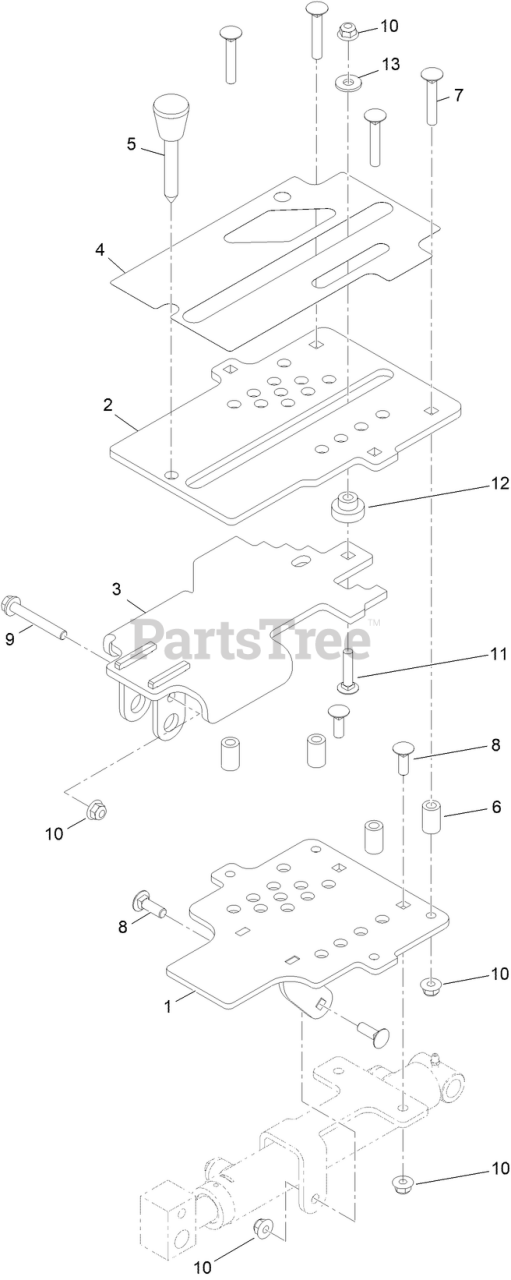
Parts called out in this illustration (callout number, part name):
1	GAUGE-DEPTH, AERATOR
2	PLATE-GAUGE, DEPTH
3	STOP-DEPTH
4	DECAL-DEPTH INDICATOR
5	PIN-HOC
7	Bolt-Carriage 3/8-16 X 2 1/4
8	Bolt-Carriage 3/8-16 X 1 1/4
9	SCREW-HFH
10	NUT-HF, NI
11	SCREW-CARR
12	BUSHING-DELRIN
13	WASHER-HARDENED
